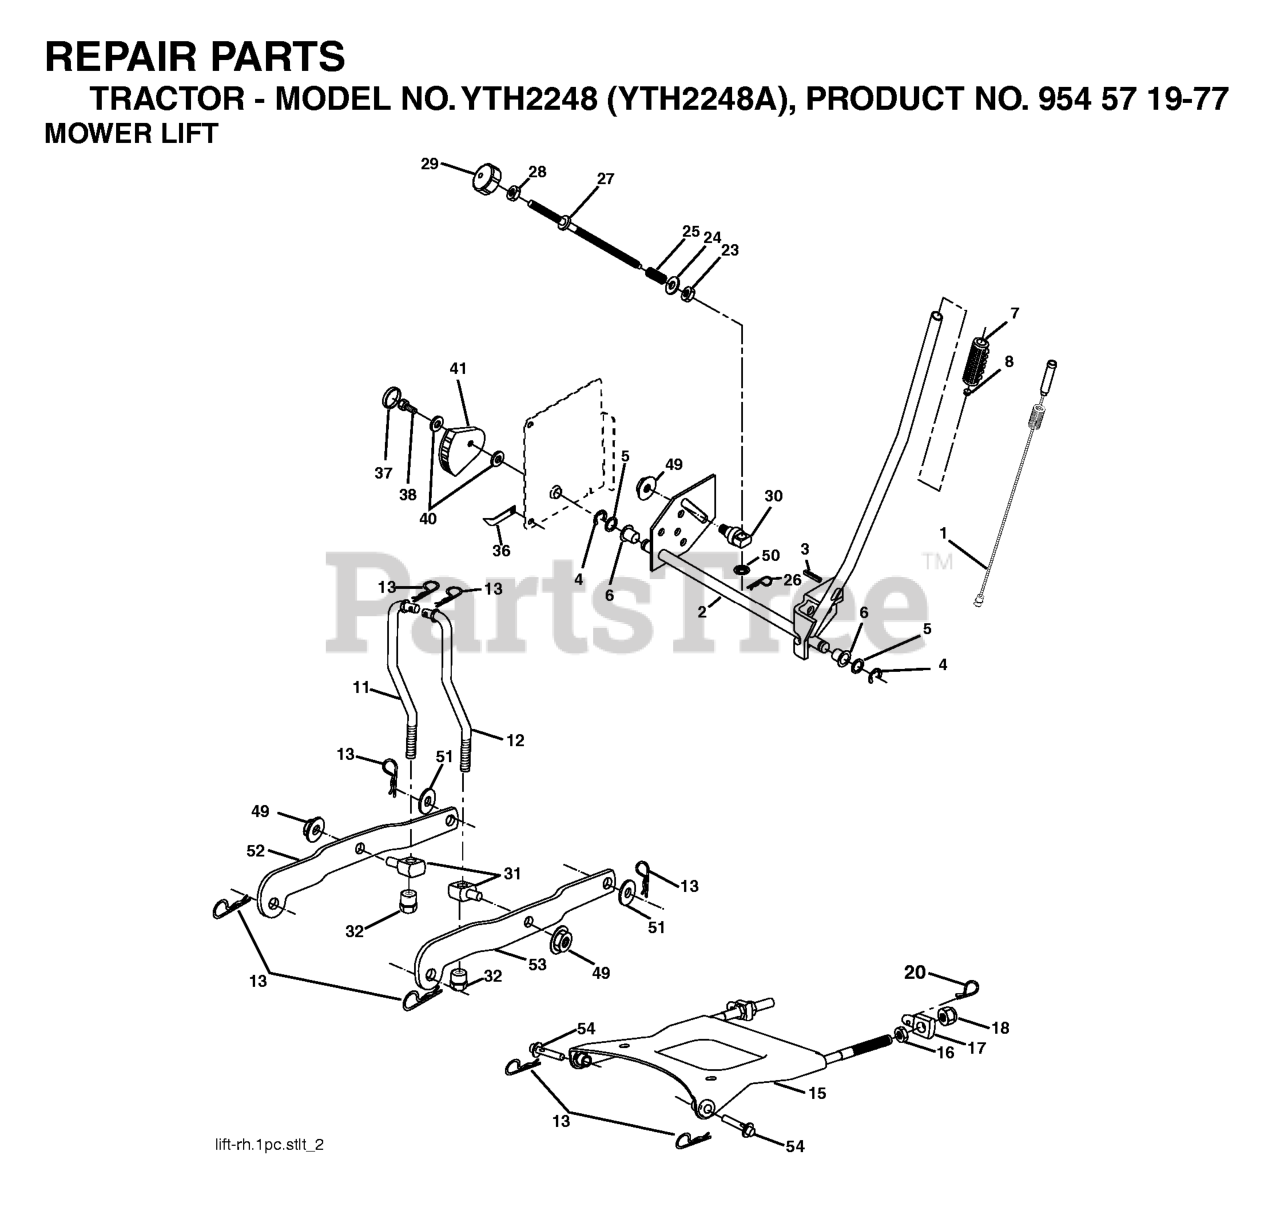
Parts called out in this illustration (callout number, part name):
1	WIRE ASM INNER W/ PLUNGER LT
2	SHAFT ASM R HANDLE
3	PIN GROOVE.
4	RETAINING RING LT
6	BEARING.NYLON
7	GRIP HANDLE
8	PLUNGER BUT KIT
11	LIFT LINK LH
12	LIFT LINK RH
13	RETAINER-SPRNG RB
15	PLATE ASM SUSP FRONT
16	NUT.HEX.JAM.1/2-13
18	NUT.LK.W/WSH.1/2.
20	SPRING RETAINER
25	SPRING**
26	RETAINER CLIP
27	ROD ADJ LIFT
28	NUT
29	KNOB INF 3/8-16
32	NUT, LIFT LINK 7/16-20
36	POINTER, HEIGHT INDICATOR(2 2)
38	SCREW 5/16-18X1
41	IND. HEIGHT STLT
49	NUT
50	NUT PUSH M
51	Washer 1 17/32 X 7/8 X 16 Ga
52	ARM SUSP. REAR LH
53	ARM SUSP REAR RH
54	PIN.FLANGE
